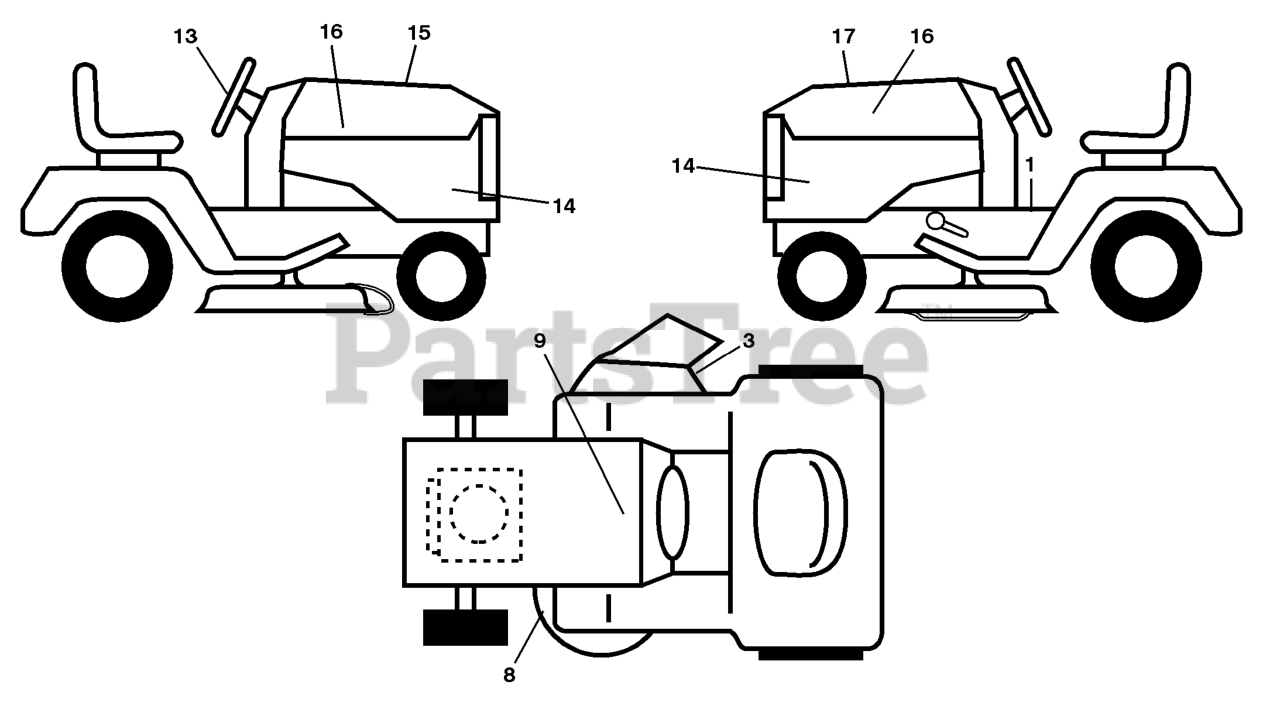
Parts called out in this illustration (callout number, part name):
1	DECAL.FENDER.WARNING.ENG
3	DECAL.WARN.KEEP.HAND.AWAY
8	DECAL V BELT SCHEMATIC
9	DECAL BTRY SYMBOLS
13	DECAL.WHEEL.STRG.LGN.H
14	DECAL, PANEL SIDE
15	DECAL HOOD CUST. RESP.
16	DECAL.HOOD.LOGO.HUSQVARNA
17	DECAL, REPLACEMENT
17	DECAL.BYPASS.FENDER.CRD.LT.YT
17	PAD.FOOTREST.LH.HUSQ.T
17	PAD.FTRST.RH.PCH.HUSQ.
17	Manual, Owner's
